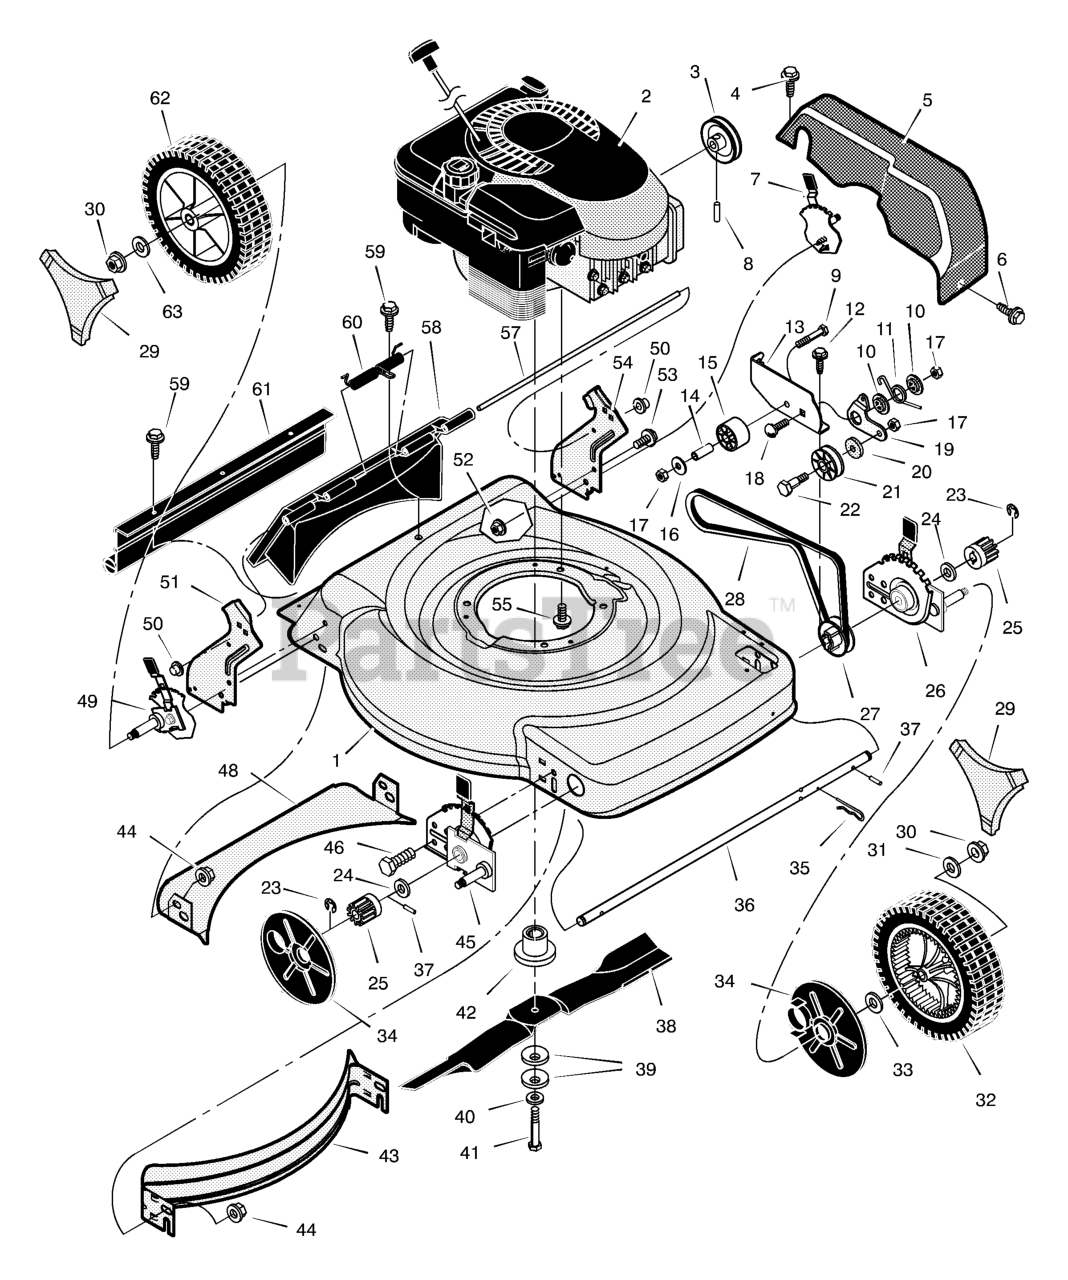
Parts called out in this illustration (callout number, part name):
1	Housing
2	Engine *
3	Pulley, Drive
5	Cover, Belt (Gray)
7	Adjuster, Left Rear Height
8	Pin, Spring
10	Spacer, Idler Arm
12	Screw
13	Bracket, Idler Support
14	Bearing, Idler
15	Pulley, Idler
17	Nut
18	Bolt, Carriage
19	Arm, Pivot
20	Spacer, Idler
21	Pulley, Idler
22	Bolt, Shoulder
25	Gear, Pinion
26	Adjuster, Left Front Height
27	Pulley, Axle
29	Cap, Hub
30	Nut, Flange
31	Washer
32	Wheel & Tire, Front
34	Cover, Dust
35	Pin, Hair
37	Pin, Drive
39	Washer, Belleville
42	Adapter, Blade
43	Baffle, Front
44	Nut, Flange
45	Adjuster, Right Front Height
46	Bolt
48	Baffle, Rear
49	Adjuster, Right Rear Height
50	Push On Cap
51	Bracket, Right Handle
52	Nut, Flange
53	Bolt
54	Bracket, Left Handle
55	Bolt, Engine
57	Rod, Pivot
58	Door, Rear (Gray)
60	Spring
61	Guard, Rear
62	Wheel & Tire, Rear
